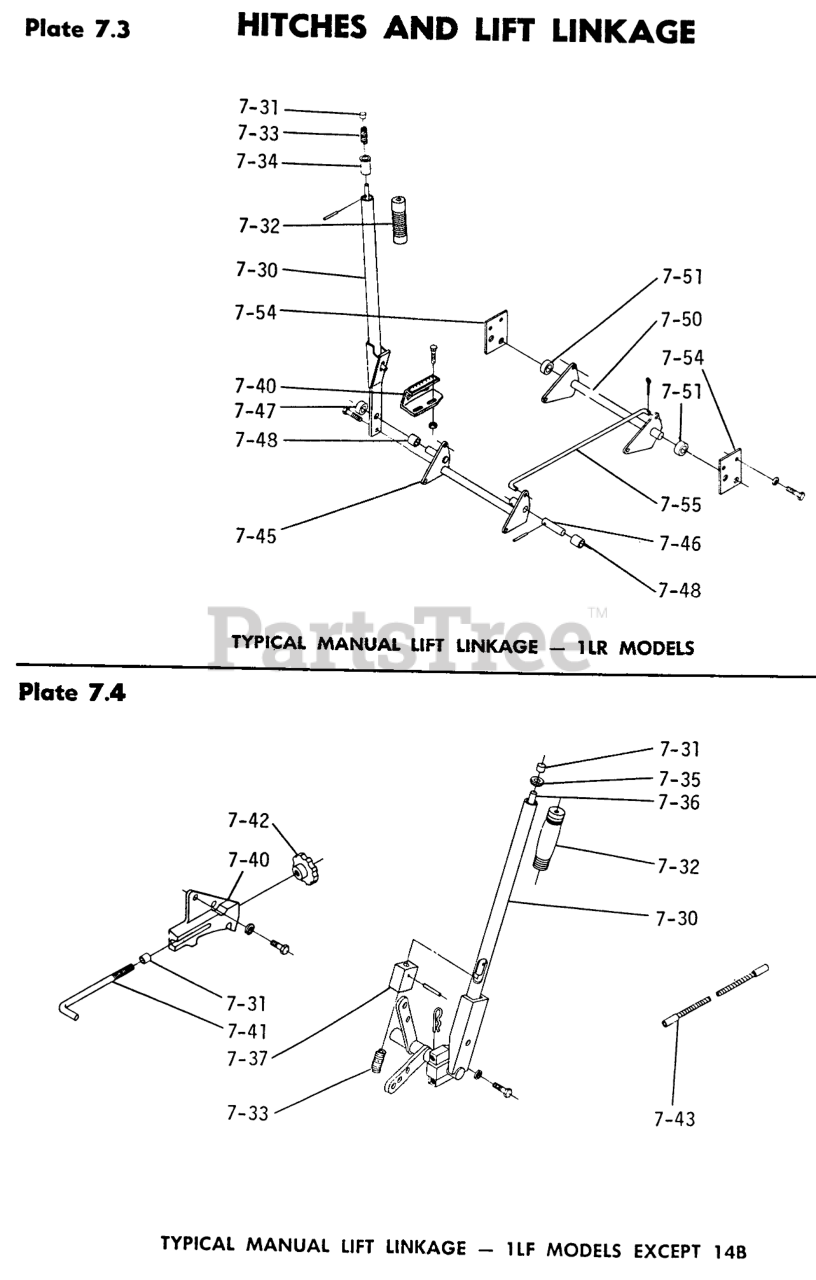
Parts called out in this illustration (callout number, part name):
7-30	Bolt 3/8-16 x 7/8
7-30	Hairpen
7-30	Bolt Hex 5/16-18
7-30	Lockwasher
7-32	HANDGRIP
7-33	SPRING-COMPRESSION
7-34	RETAINER-SPRING
7-34	PIN-SPIROL
7-37	Roll Pin
7-40	Bolt Hex 5/16-18 x 3/4
7-40	Nut-Nylok
7-42	KNOB-LIFT CONTROL
7-42	Bolt 3/8-16 x 3/4
7-42	Lockwasher
7-45	Front Lift Rod
7-46	ROLLPIN 3/16 X 7/8
7-49	Retainer
7-49	Bolt-Carriage 5/16-18
7-49	Nut-Nylok
7-50	Rear Lift Rod
7-51	SPACER
7-54	Bolt, 5/16-18 x 5/8
7-54	Lockwasher
7-55	Hairpin
